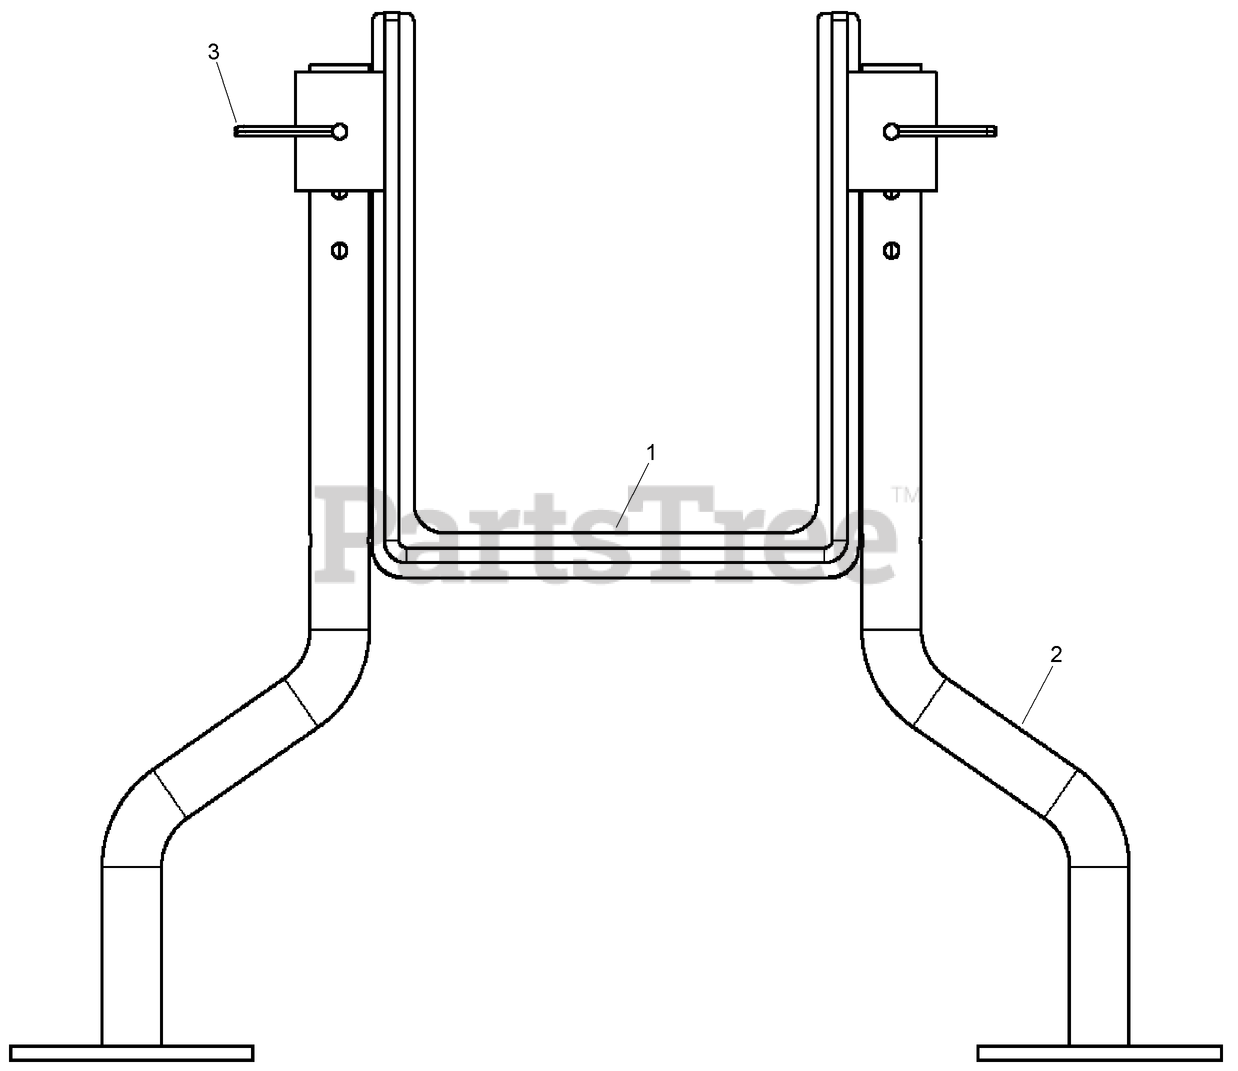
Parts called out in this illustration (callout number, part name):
1	WELDMENT - Plow Stand
2	WELDMENT - Leg, Plow Stand
3	PIN - Snapper
